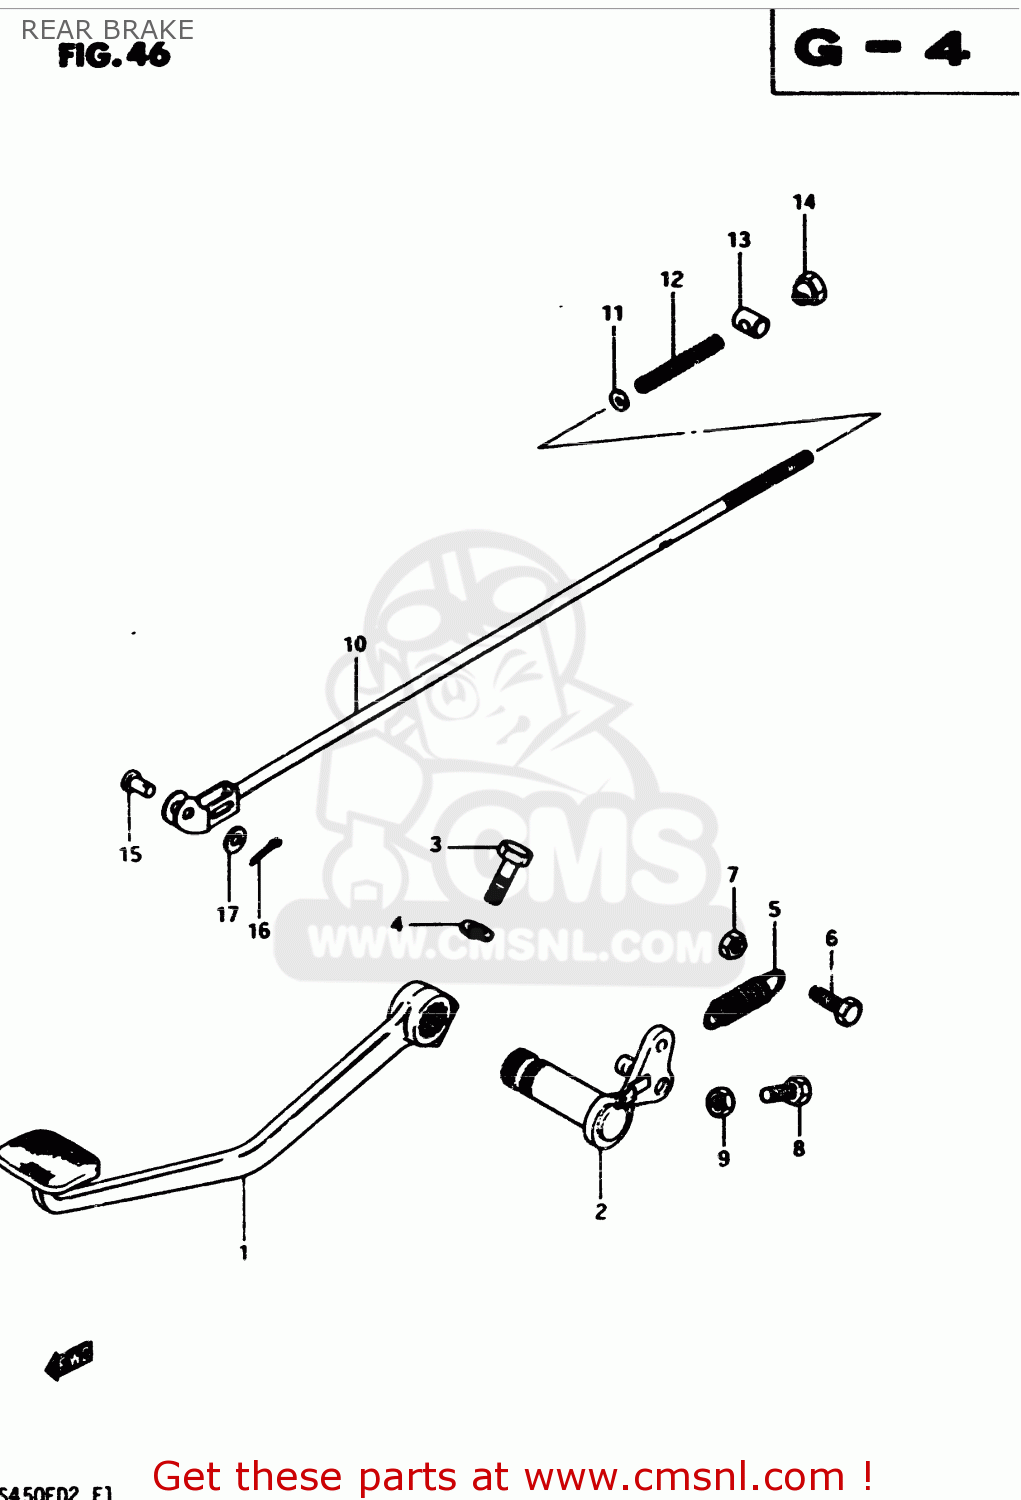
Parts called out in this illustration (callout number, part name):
1	PEDAL,BRAKE
2	ARM,BRAKE PEDAL
3	BOLT
4	LOCK WASHER
5	SPRING
6	BOLT
7	NUT
8	BOLT
9	NUT
10	ROD ASSY,RR BRAKE
11	WASHER
12	SPRING
13	PIN
14	NUT
15	PIN(L:13.5)
16	PIN 20X20
17	WASHER
